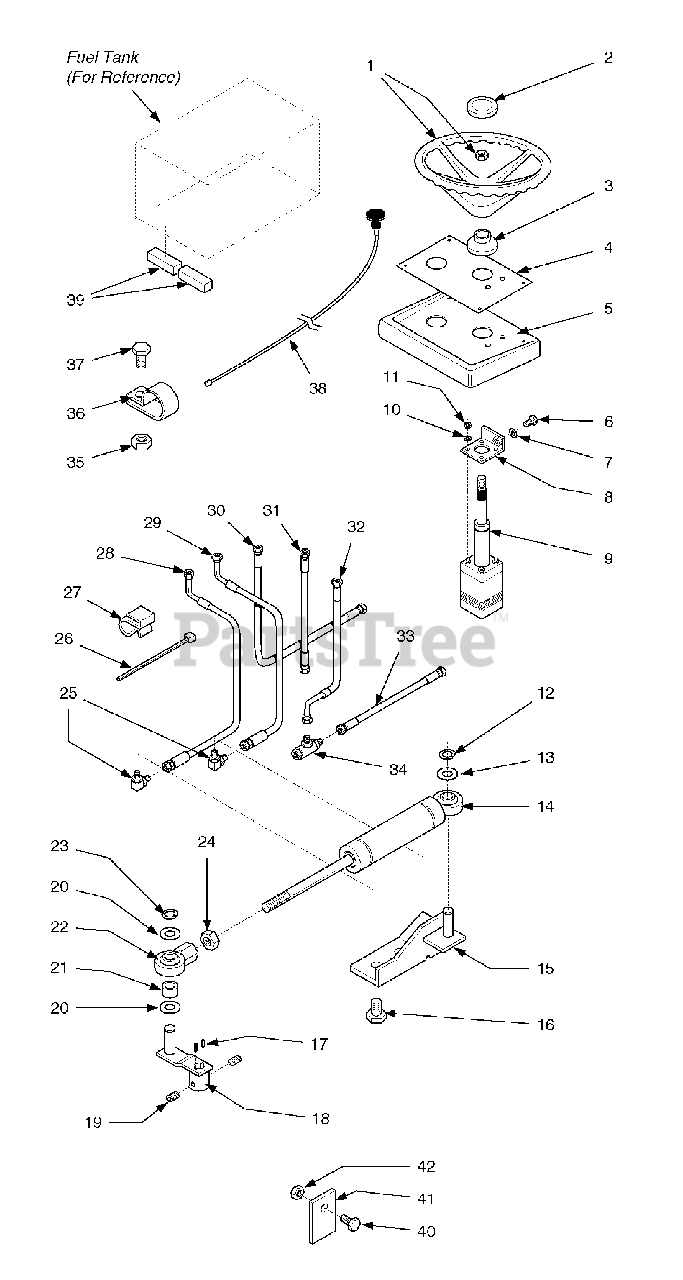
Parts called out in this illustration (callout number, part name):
1	Steering Wheel Assembly
2	Cap, Steering Wheel
3	Boot, Steering Stem
4	Decal, Dash
5	Instrument Panel
6	Hex Hd. Cap Screw, M12
7	Lockwasher, 1/2
8	Mounting Plate
9	Hydrostatic Motor, Steering Unit
10	Lockwasher, 3/8
11	Nut, Hex 3/8 X 18 M12 X 1.75 X 20mm
12	Retaining Ring, 5/8"
14	Cylinder, Power Steering**
15	Bracket Assembly, Cylinder
16	Screw, Hex Washer TapTite, 3/8 x 16 x 3/4"
17	Key, Square
18	Arm Assembly
19	Set Screw, Sqr. Hd.
20	Washer
21	Spacer
22	Rod End/Ball Joint Assembly
23	Retaining Ring, 3/4"
24	Nut, Hex 3/4 x 16
25	Fitting, Hydraulic 90° 5/8 x 18 - 5/8 x 18
26	Tie, Self-Locking
28	Hose Assembly, Hydraulic (Steer RT to Cylinder)
29	Hose Assembly, Hydraulic (Steer LT to Cylinder)
30	Hose Assembly, Hydraulic (Steer IN to Pump)
31	Hose Assembly, Hydraulic (Steer AUX to Lift)
32	Hose Assembly, Hydraulic (Steer OUT to Tee Fitting)
33	Hose Assembly, Hydraulic (Return "T" to Pump)
34	Fitting, Hydraulic Tee
35	Nut, Hex Ctr Lock 1/4 x 20
36	Clamp, Hose
37	Screw, Hex Hd Cap, 1/4 x 20 x 1"
38	Choke, Control
39	Pad, Neoprene
40	Screw, Hex Hd Cap, 3/8 x 16 x 1"
41	Plate, Upstop
42	Nut, Hex Flange Lock, 3/8 x 16
